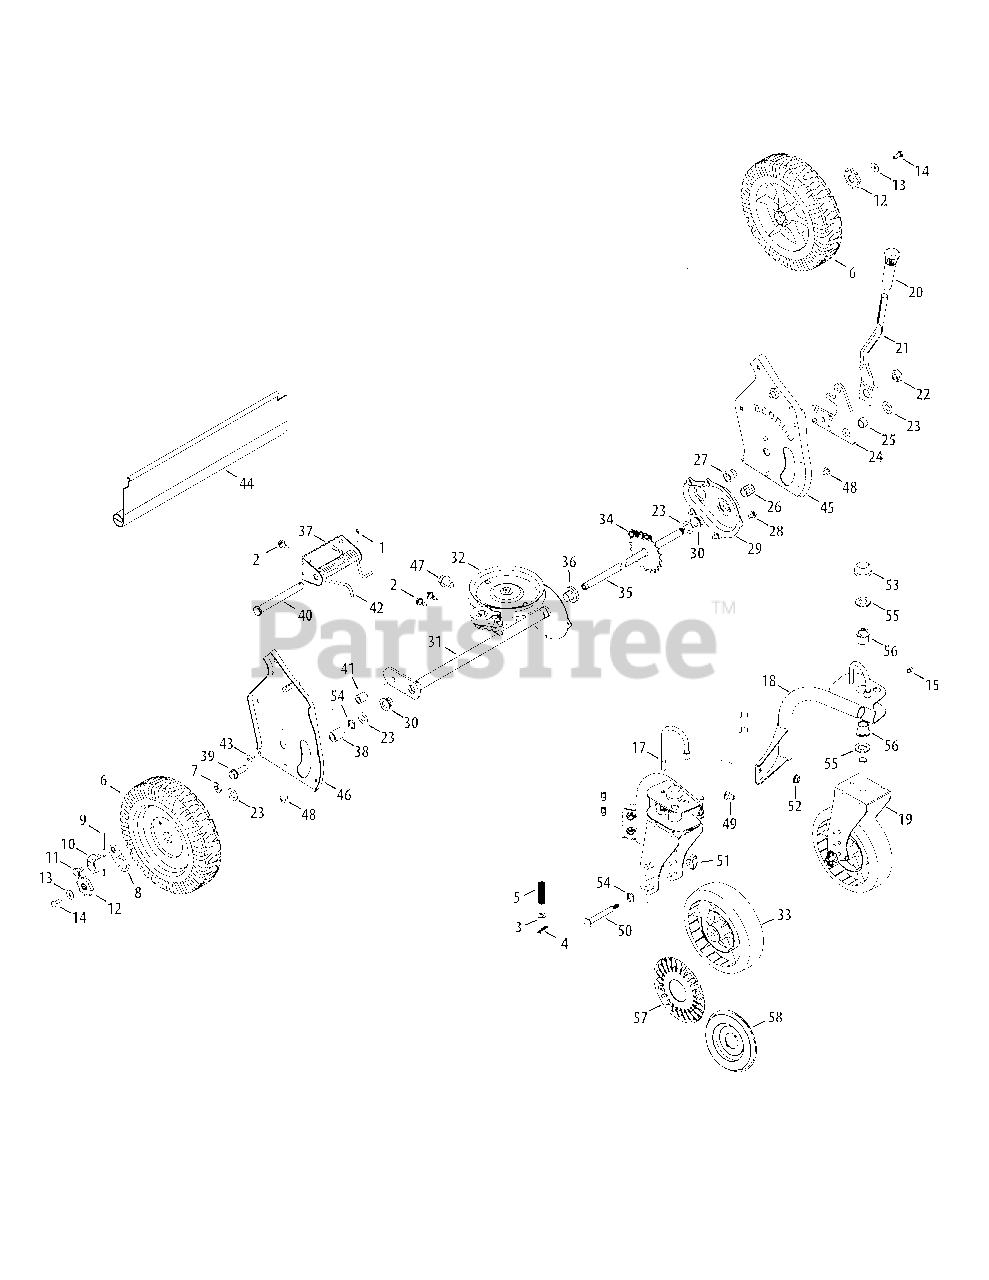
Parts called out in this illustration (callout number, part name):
1	Cotter Pin
2	Screw 1/4-14 x .825
3	Flat Washer.330 ID x.630 OD
4	Cotter Pin
5	Compression Spring
6	Wheel, 9 x 2.125 Bar
7	Top Lock Tab Weld Nut 1/4-20
8	Ratchet Pawl Plate
9	Plastic Spring Ratchet
11	Shlder Screw.340 ID x.285 OD
12	Wheel Ratchet
13	Bell Washer.265 ID x.75 OD
14	Hex Cap Screw 1/4-20 x.620
15	Grease Fitting
16	Hubcap - Radial Spoke
17	Wheel Pin Lock
21	Spring Lever
22	Shoulder Nut.825 x .165 Lg.
23	Flat Washer .508 ID x 1.0 OD
24	Pivot Arm Assembly
25	Spacer .510 ID x .70 OD
26	Slv Bearing .504 ID x .830 OD
27	Shlder Spacer, .385ID x .715Lg
28	Tap Screw 1/4-20 x .375
29	Chain Cover Assembly
30	Flge Bearing .506 ID x .590 Lg
31	Transmission Axle Assembly
32	Transmission Ass’y Complete
33	Wheel 7 x 2
35	Rear Axle Assembly
36	Flge Bearing .506 ID x .715 Lg
37	Height Adjustment Spring Brkt.
38	Spacer .550 ID x .750 OD
39	Screw 3/8-16 x .25
40	Clevis Pin .50 Dia x 4.82 Lg.
41	Spacer .385 ID x .624 OD
42	Torsion Spring
43	AB Screw, #10-16 x .500
44	Trail Shield
47	Screw, 5/16-18 x .625
48	Screw 1/4-14 x.500
49	Carriage Bolt 5/16-18 x.62
50	Caster Axle
52	Flange Lock Nut 5/16-18
54	Wave Washer.510 ID x.750 OD
55	Flat Washer.640 ID x 1.12 OD
56	Flange Bearing
57	Hubcap - Spoke w/ Hole
58	Hubcap - Radial Spoke
